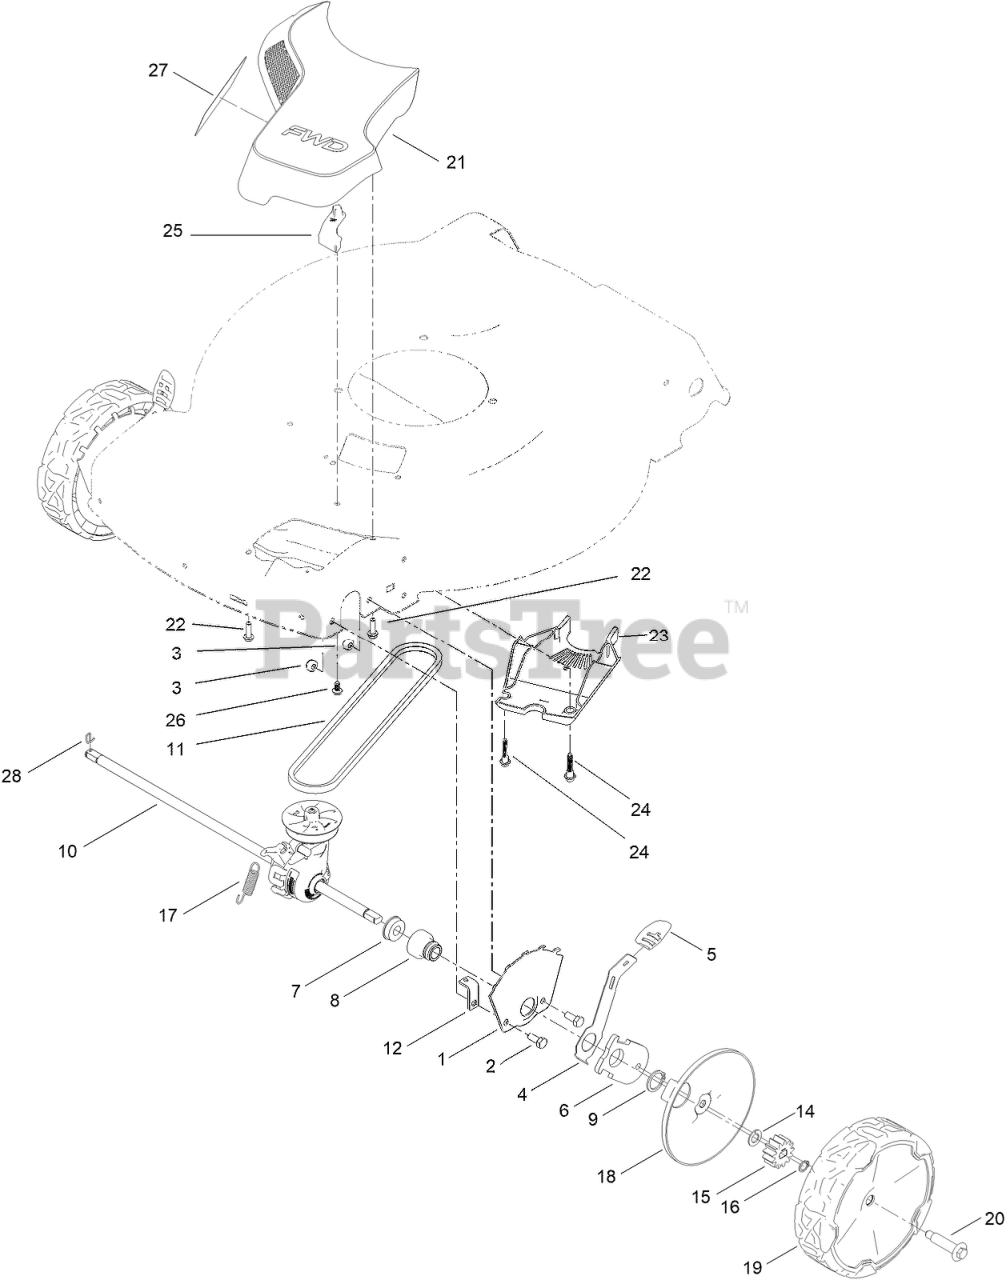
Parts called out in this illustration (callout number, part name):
1	PLATE-HOC,FRONT FSVQ WEDNESDAY
2	SCREW-HH
3	NUT-LOCK, NI
4	ARM-SPRING
5	KNOB-LEVER, HOC
6	ARM-PIVOT, FRONT
7	BEARING-BALL
8	RETAINER-BEARING, HOC
9	RING-RETAINING
10	TRANSMISSION-FWD
11	V-BELT
12	TAB-MOUNT, CABLE
14	WASHER-THRUST
15	GEAR-PINION, 13T
16	RING-RETAINING
17	SPRING-EXTENSION
18	ASM-COVER, WHEEL (DK GRAY)
19	ASM-8" WHEEL, FWD (BUSHINGS)
20	WHEEL BOLT
21	ASM-INTAKE, FWD
22	SCREW-HWH
23	COVER-BELT, LOWER (AWD)
24	SCREW-SHOULDER, HHF
25	PAD-STOP
26	SCREW-PLASTIC,PH
28	PIN-SNAP
